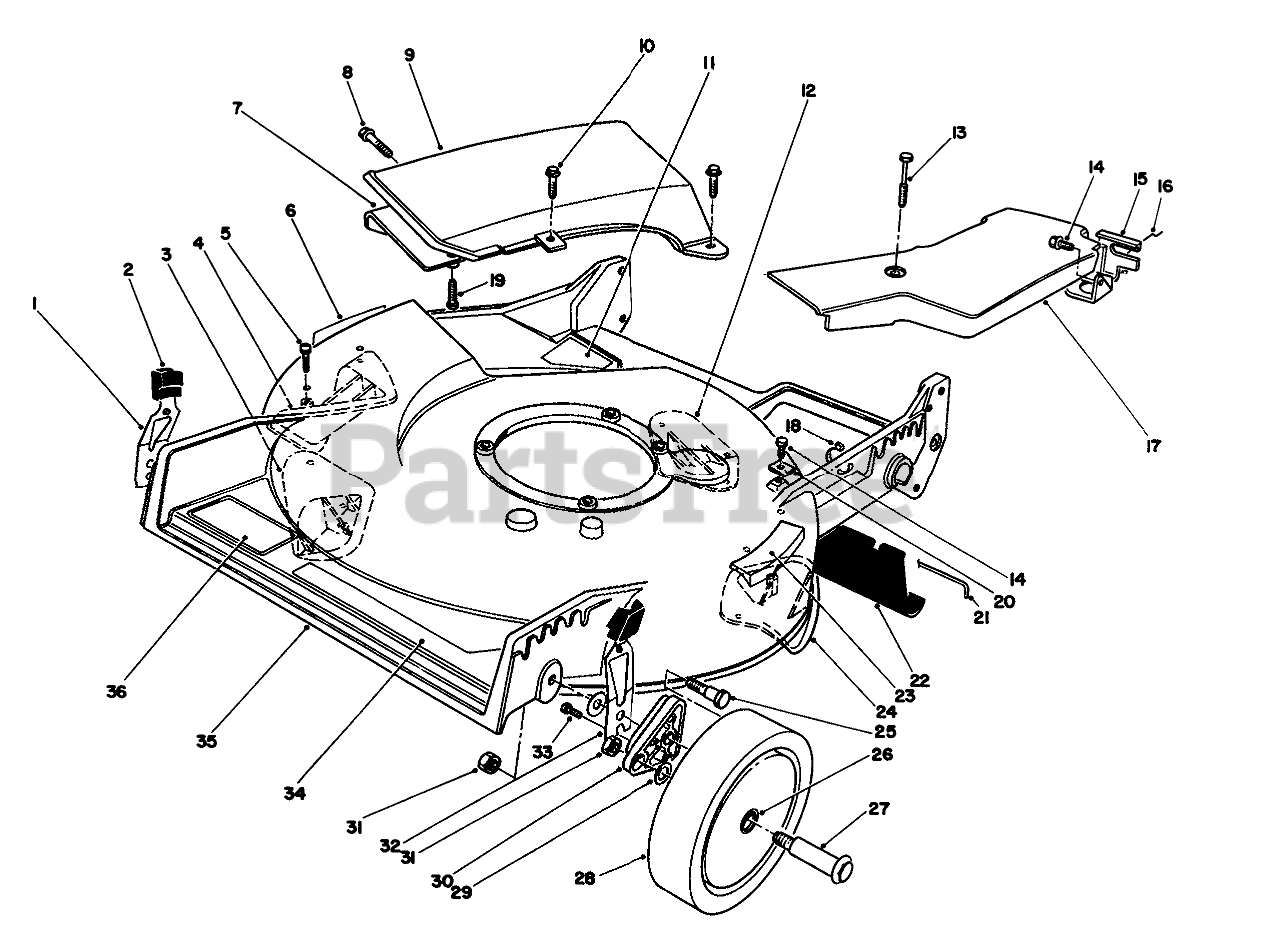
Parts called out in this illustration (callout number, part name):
1	RH SPRING ARM ASSEMBLY
2	KNOB-ARM
3	KICKER
4	KICKER
5	#8 X .625" PHILPS PAN H
6	DECAL-DANGER
7	Deflector-Recycler
8	SCREW AND WASHER ASM
9	Cover Assembly (Incl. Ref. #7 & 19)
10	SCREW-HWH
11	DECAL - DANGER
12	KICKER
13	SCREW-HHFTF
14	SCREW-HWHTF
15	Bracket-Adj. Trac
16	RETAINER-CABLE
17	BELT COVER
18	TIE-CABLE
19	Screw-Pan Hd.
20	CLAMP-CABLE
21	ROD-SHIELD
22	SHIELD-TRAILING
23	STEP PAD DECAL
24	KICKER
25	SCREW-SHOULDER
26	BUSHING
27	WHEEL BOLT
28	Wheel & Tire Assembly (Incl. Ref. #26)
29	WASHER
30	ARM-PIVOT, FRONT
31	Nut
32	LH SPRING ARM ASSEMBLY
33	SCREW-HWH
34	DECAL - DECK
35	Housing (Incl. Ref. #3-6, 12, & 24)
36	DECAL
